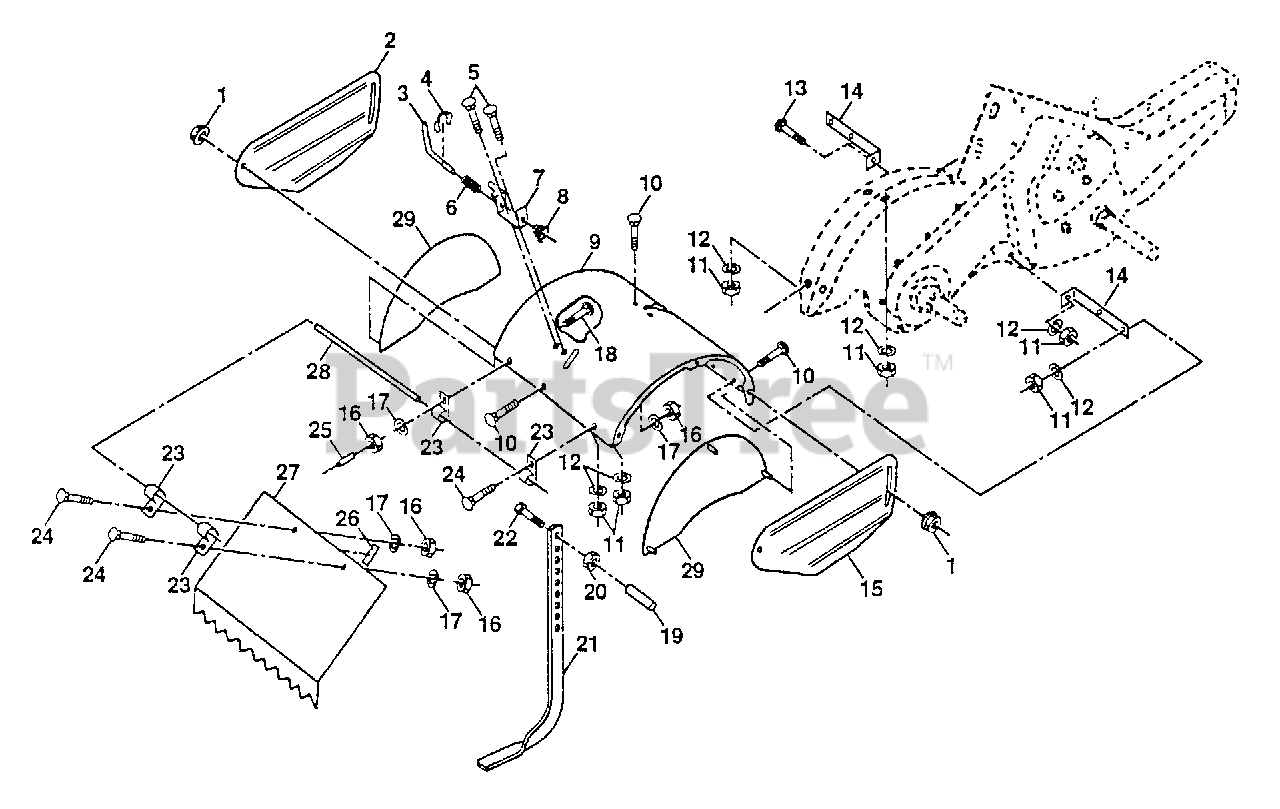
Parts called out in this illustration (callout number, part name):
1	NUT
2	SHIELD.SD.OUT.LH
3	STAKE PIN TI
4	KLIP RING TI
5	BOLT CRT
6	SPRING TI
7	LATCH BRACKET TI
8	SPRING CRT
10	BOLT
11	NUT.HEX.5/16-18
12	LOCKWASHER
13	BOLT
14	BRKT SHIELD TINE
15	SHIELD.SD.OUT.RH
17	LOCKWASHER
18	BOLT
19	GRIP CRT
20	NUT.HEX.3/8-16UNC
22	BOLT
23	HINGE CRT
24	BOLT
25	VINYL CAP TI
26	PAD IDLER TI
28	PIN HINGE
29	SHLD SIDE
